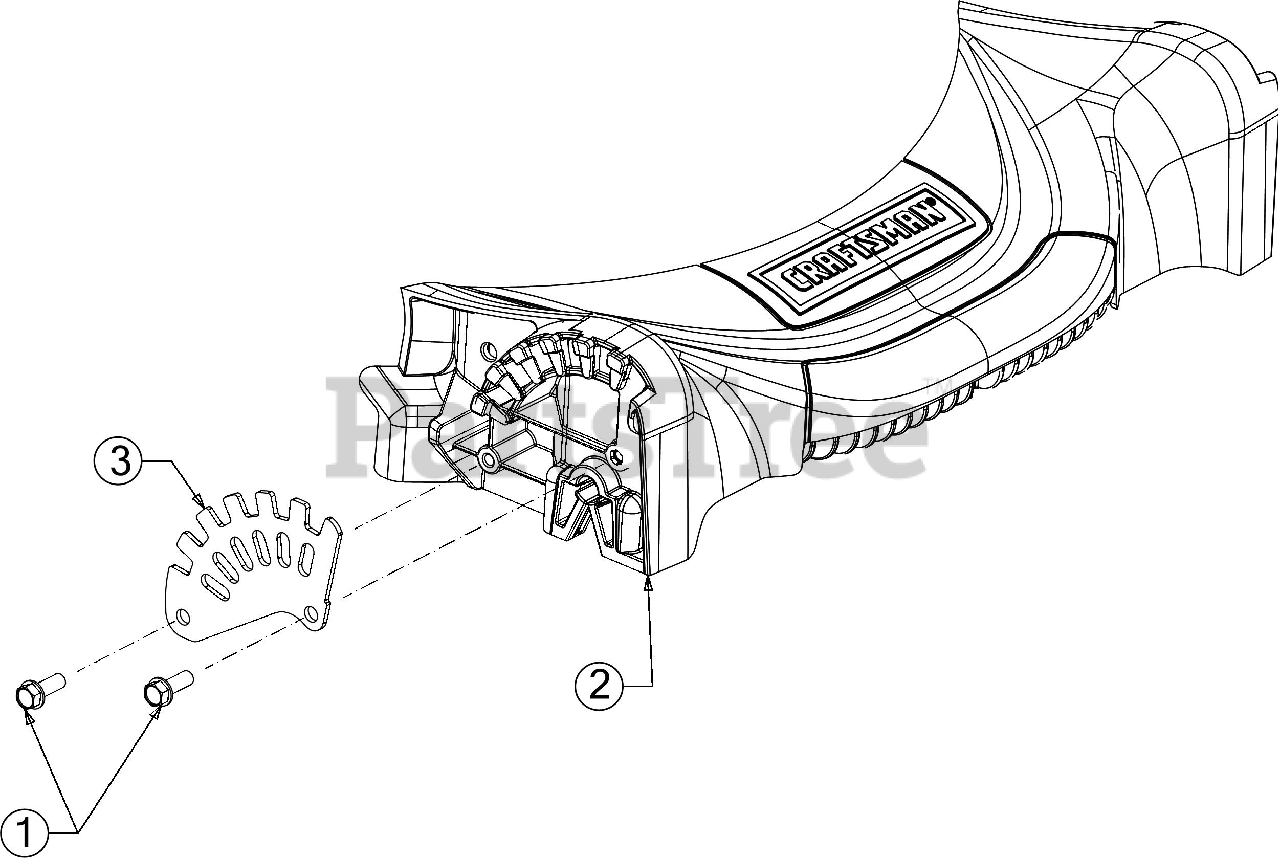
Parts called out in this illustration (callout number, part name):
1	SCREW 1/4-15 X .750
2	FRONT AXLE COVER
3	HEIGHT ADJUSTMENT PLATE
